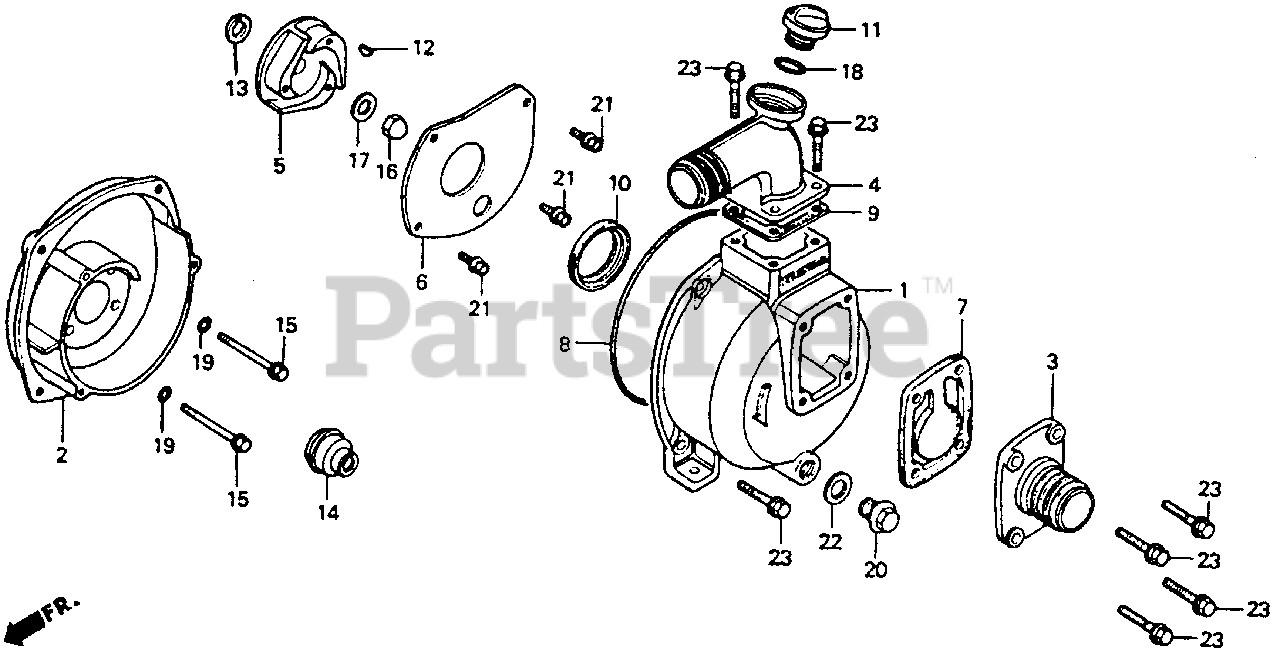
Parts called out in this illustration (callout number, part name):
2	COVER, CASE (NOT AVAILABLE)
3	MOUTH, IN. (NOT AVAILABLE)
4	MOUTH, OUTLET (NOT AVAILABLE)
6	DISK, FRICTION
7	VALVE, IN.
8	RING, CASING SEAL
9	GASKET, OUTLET
10	RING, CENTER SEAL
11	CAP, FILLER
12	KEY, IMPELLER
13	SHIM, ADJUSTER
14	SEAL ASSY., MECHANICAL WATER
15	BOLT, PUMP SETTING
16	NUT, IMPELLER
17	WASHER (13MM)
18	O-RING, FILLER CAP
19	O-RING (7.5MM)
20	BOLT, DRAIN PLUG (20MM)
21	BOLT-WASHER (8X20)
22	WASHER, DRAIN PLUG (20MM)
23	BOLT, FLANGE (10X28)
